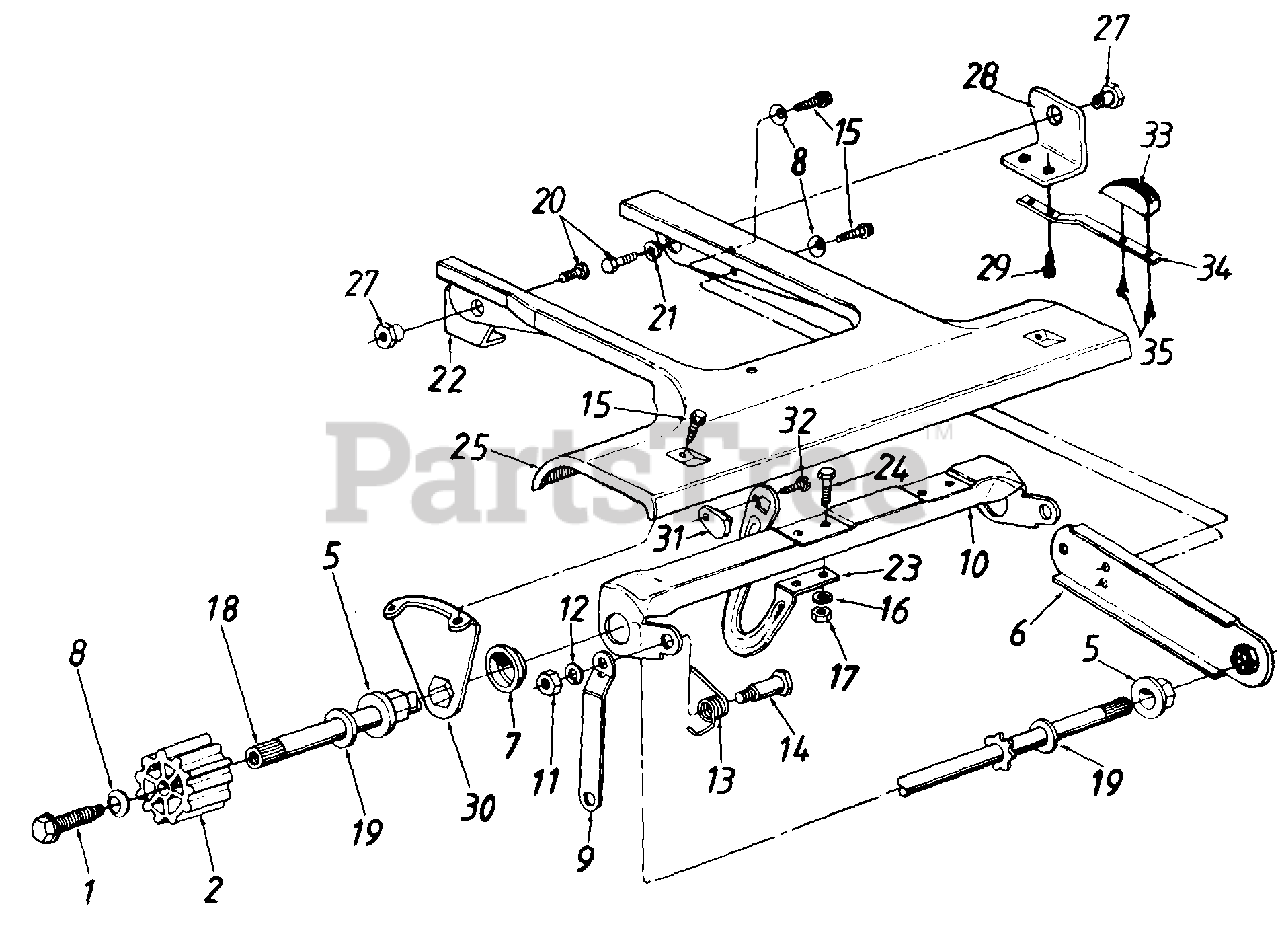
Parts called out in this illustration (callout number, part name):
1	Hex Wash. Hd. Tap Scr. 1/4-20 x .75" Lg.
2	Wheel Drive Pinion
5	Hex Flange Brg..504" I.D.
8	Bell-Wash..265" I.D. x .75" O.D.
11	Hex Nut 5 16-18 Thd.
12	L-Wash. 5/16" I.D.
13	Torsion Spring - R.H.
14	Shoulder Bolt .437" Dia.
15	Hex Wash. Hd. AB-Tap Scr. 1/4 x .62" Lg.
16	L-Wash. 1/4" I.D.
17	Hex Nut 1/4-20 Thd.
18	Drive Shaft Ass'y.
19	Fl-Wash.,531" I.D. x .93" O.D.
20	Hex Bolt 3/8-16 x .5" Lg.
21	L-Wash, 3/8" l.D.
32	Hex B-Tap Scr. #10 x .44" Lg.
33	Chain Tensioner
34	Cantilever Spring
35	Hex B-Tap Scr. #10 x .38" Lg.
